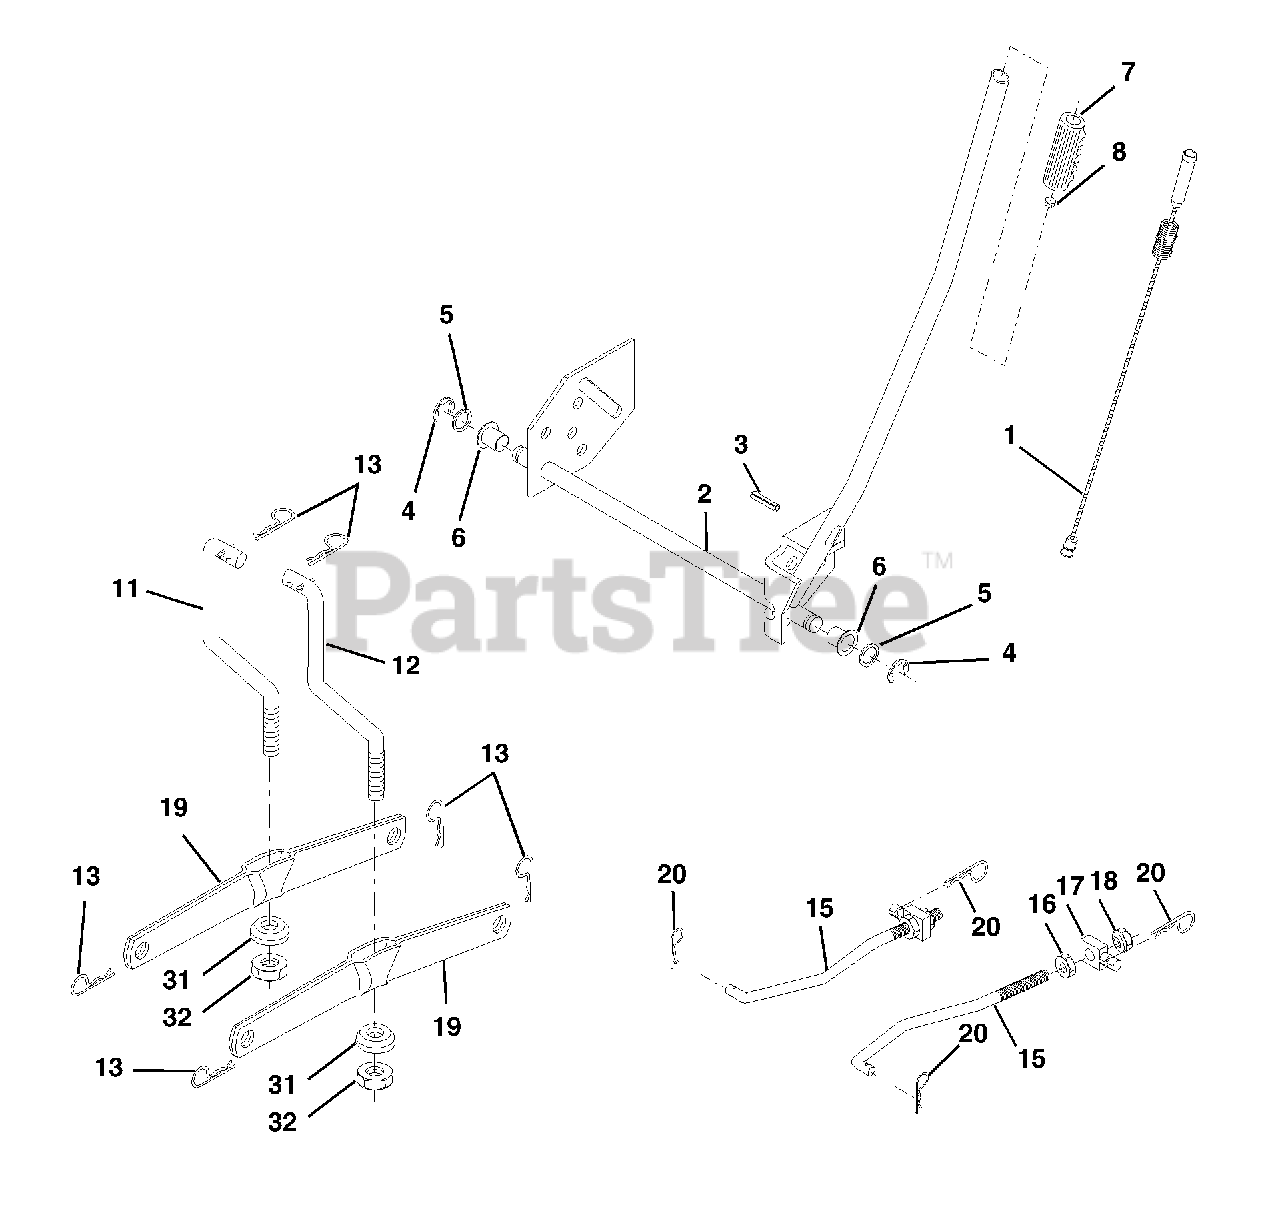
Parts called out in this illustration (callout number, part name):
1	Wire Asm Inner/Sprg w/plunger
2	Shaft Asm Lift RH
3	Pin Groove 1 500 Zinc
4	E Ring #5133-62
5	Washer 21/32 X 1 X 21 Ga
6	Bearing Nylon Blk 629 Id
7	Grip Handle Bicycle Matte Blk
8	Button Plunger Black
11	Link Lift LH Fixed Length
12	Link Lift RH Fixed Length
13	Retainer Spring
15	Link Front
16	Nut Jam Hex 1/2-13 Unc
17	Trunnion
18	Nut Lockw/Wsh 1/2-13 Unc
19	Arm Suspension Rear
20	Retainer, Spring
31	Bearing Pvt Lift
32	Nut Crownlock 3/8-24
